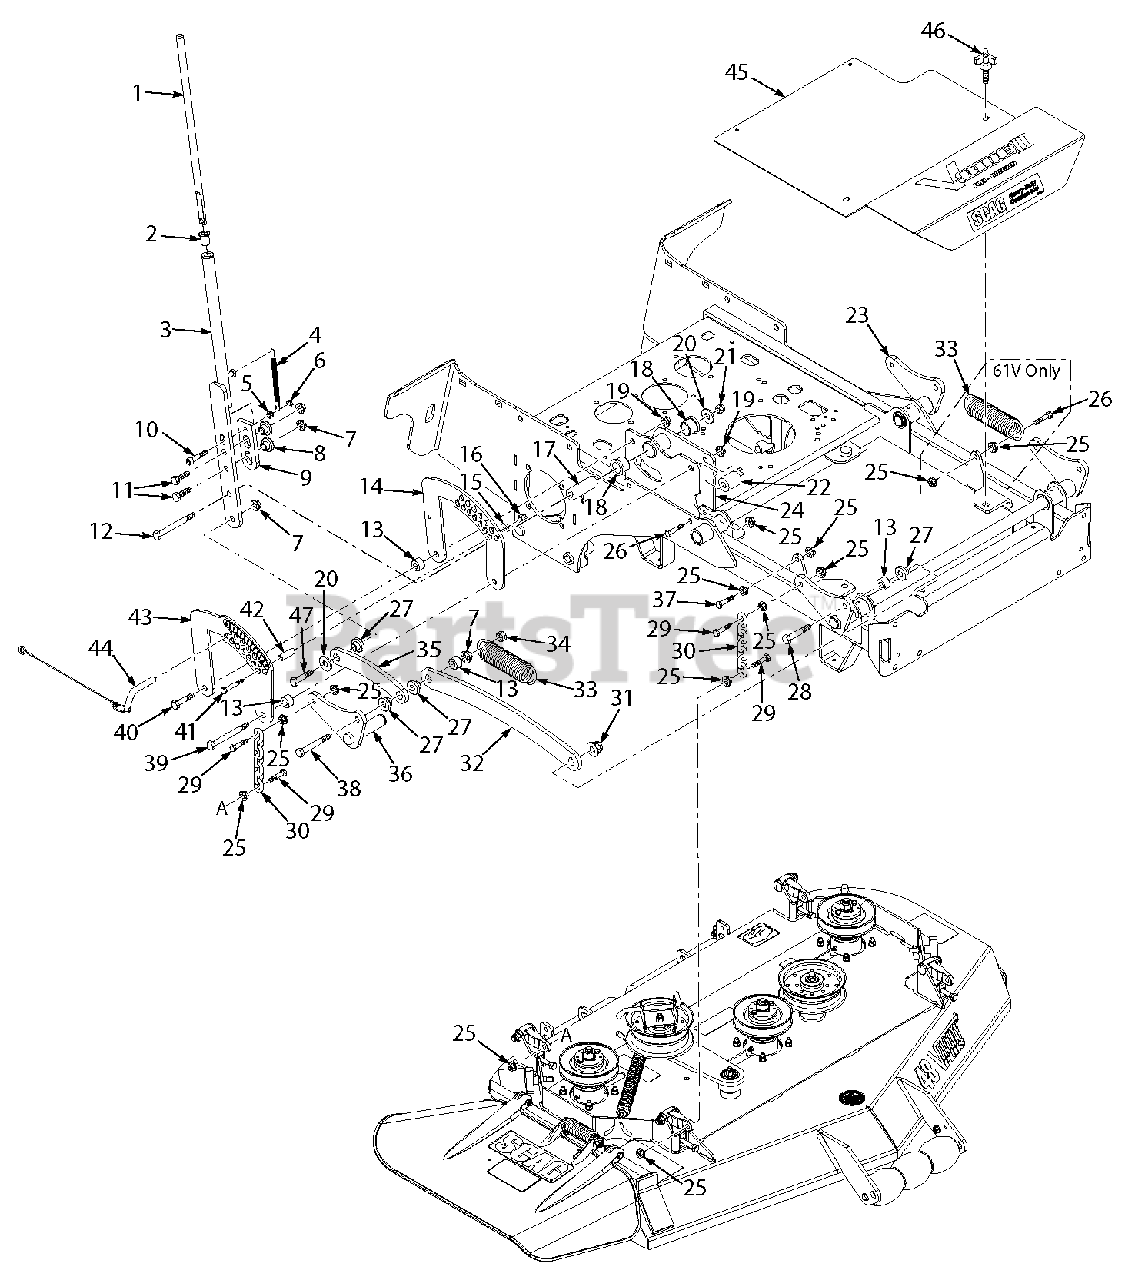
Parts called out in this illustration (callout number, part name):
1	Rod, Actuator
2	Bearing
3	Handle Weldment, Deck Latch
4	Spring, Deck Latch
5	Nut, Elastic Stop 3/8-16
6	Nut, Center Lock 3/8-16
7	Nut, Serrated Flange 1/2-13
8	Bushing, Deck Latch
9	Deck Latch, Outer
10	Capscrew, Socket Head 3/8-16 x 1-3/4"
11	Bolt, Hex Head 1/2-13 x 1-3/4"
12	Bolt, Hex Head 1/2-13 x 4-1/4"
13	Spacer
14	Bracket, Deck Height
15	Flatwasher, 3/8-.391 x .938 x .105
16	Nut, Elastic Stop 3/8-16
17	Sleeve, Pivot
18	Bearing
19	Nut, Serrated Flange 1/2-13
20	Flatwasher, 1/2-.562 x .375 x .109
21	Nut, Elastic Stop 1/2-13
22	Spacer
23	Arm Weldment, LH
24	Deck Lift Pivot Assy.
25	Nut, Serrated Flange 3/8-16
26	Bolt, Hex Head 3/8-16 x 1"
27	Bushing, Deck Latch
28	Bolt, Hex Head 1/2-13 x 2-1/2"
29	Bolt, Hex Head 3/8-16 x 1-1/2"
30	Chain
31	Nut, Flange Elastic Stop 1/2-13
32	Link, Deck Lift
33	Spring, Deck Lift
34	Nut, Center Lock 1/2-13
35	Link, Deck Lift
36	Arm Weldment, RH
37	Bolt, Hex Head 3/8-16 x 1-1/2"
38	Bolt, Hex Head 1/2-13 x 2-1/2"
39	Bolt, Hex Head 1/2-13 x 4"
40	Bolt, Hex Head 1/2-13 x 2"
41	Bolt, Hex Head 3/8-16 2-1/4"
42	Spacer
43	Bracket, Deck Height - Outer
44	Pin Assy. w/Lanyard
45	Belt Cover w/Decals
46	Knob w/Stud
47	Bolt, Hex Head 1/2-13 x 1-3/4"
